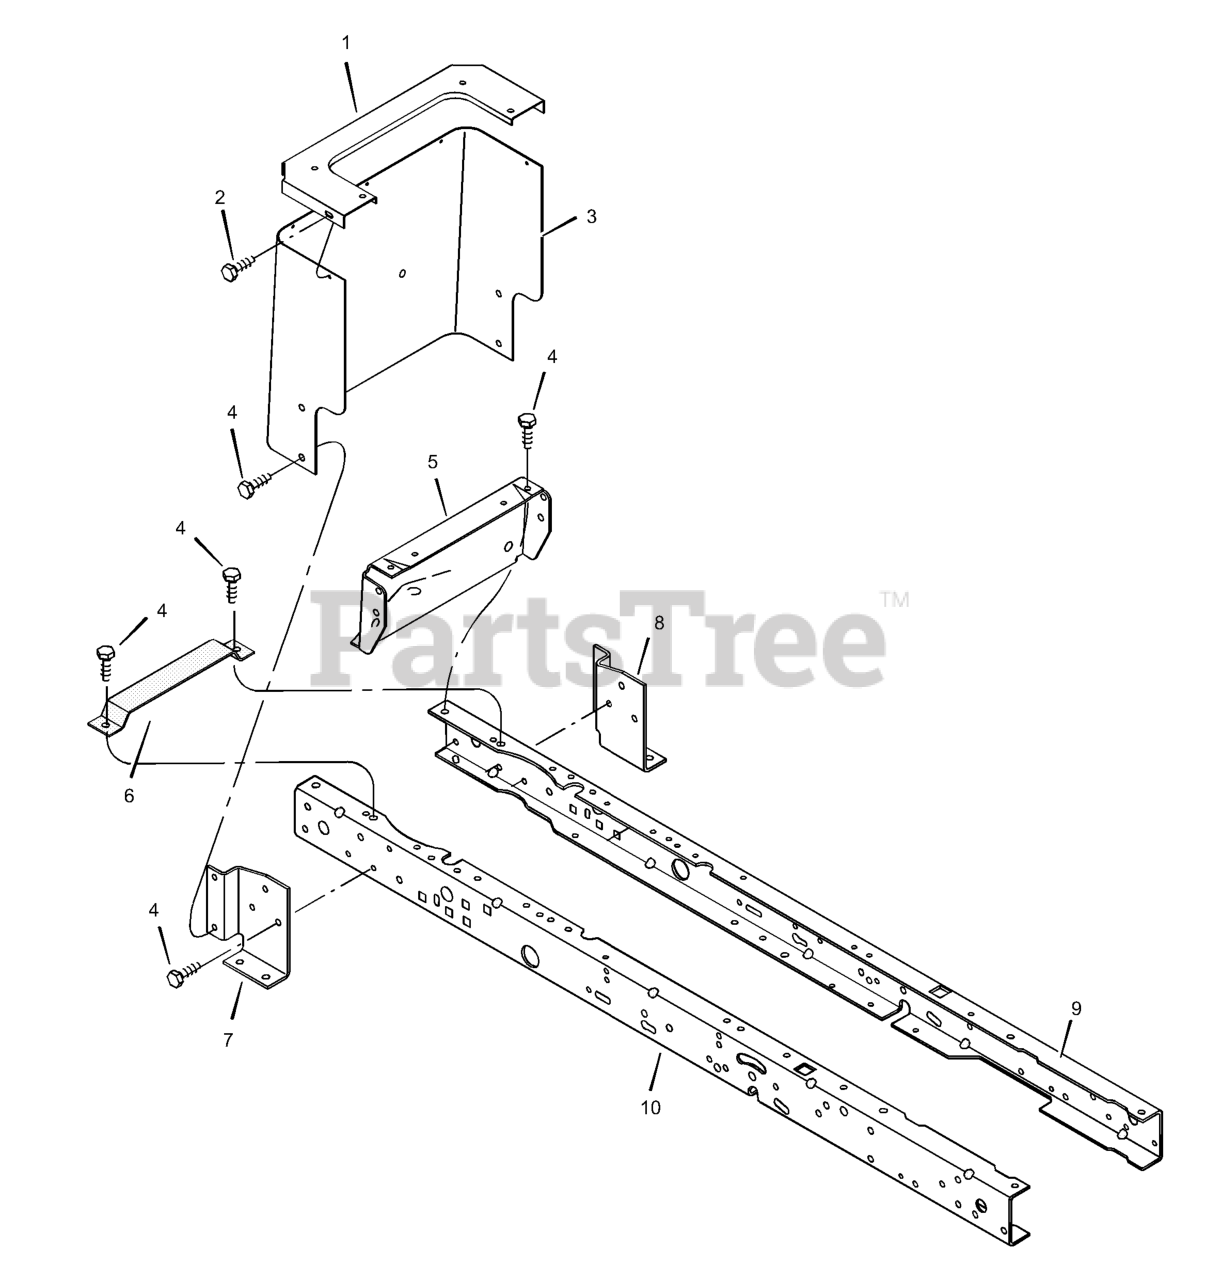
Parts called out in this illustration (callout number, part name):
1	Plate, Top Rear
2	Screw
3	Plate, Rear
5	Plate, Hitch
6	Bracket, Support
7	Bracket, Right Transaxle
8	Bracket, Left Transaxle
9	Frame, Left
10	Frame, Right
